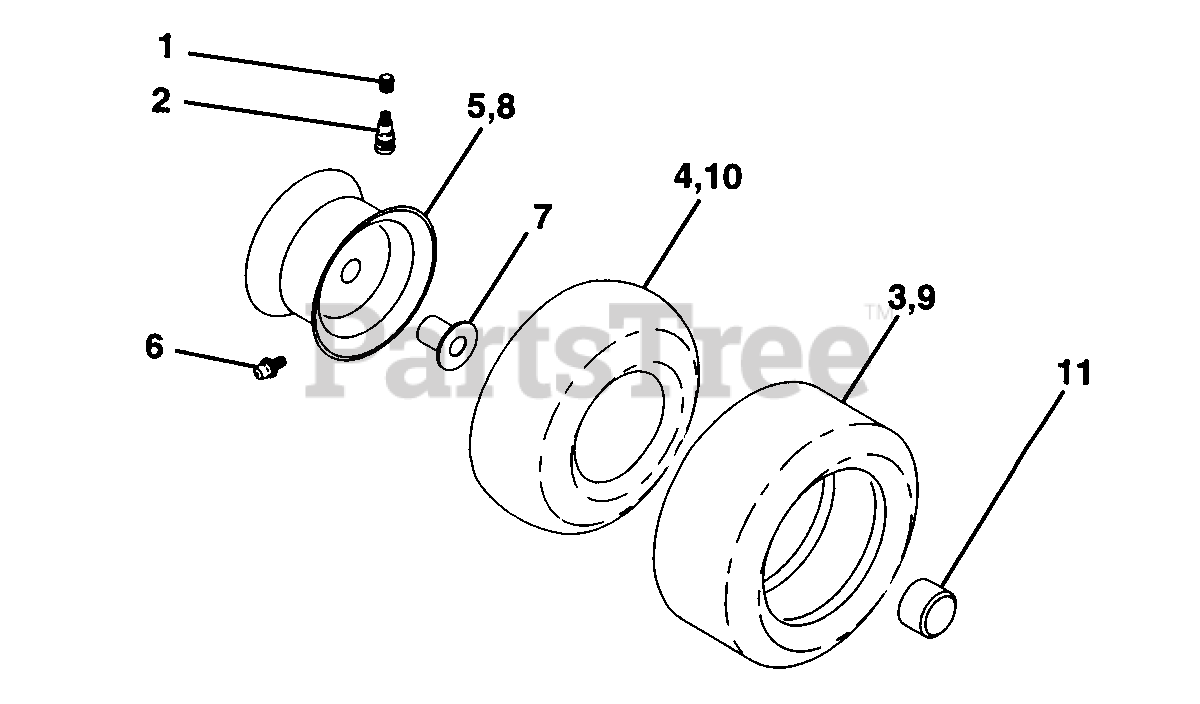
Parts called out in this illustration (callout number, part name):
1	Cap Valve Tire
2	Stem Valve
3	Tire F Ts 15 X 6 0 - 6 Service
4	Tube Front (Service Item Only)
5	Rim Asm 6"front Silver Service
6	Fitting Grease (Front Wheel Only)
7	Bearing Flange (Front Wheel Only)
8	Rim Asm 8" rear Silver Service
9	Tire R Ts 18x8 5-8 C Service
10	Tube Rear (Service Item Only)
11	Cap Axle Blk 1 50 X 1 00
